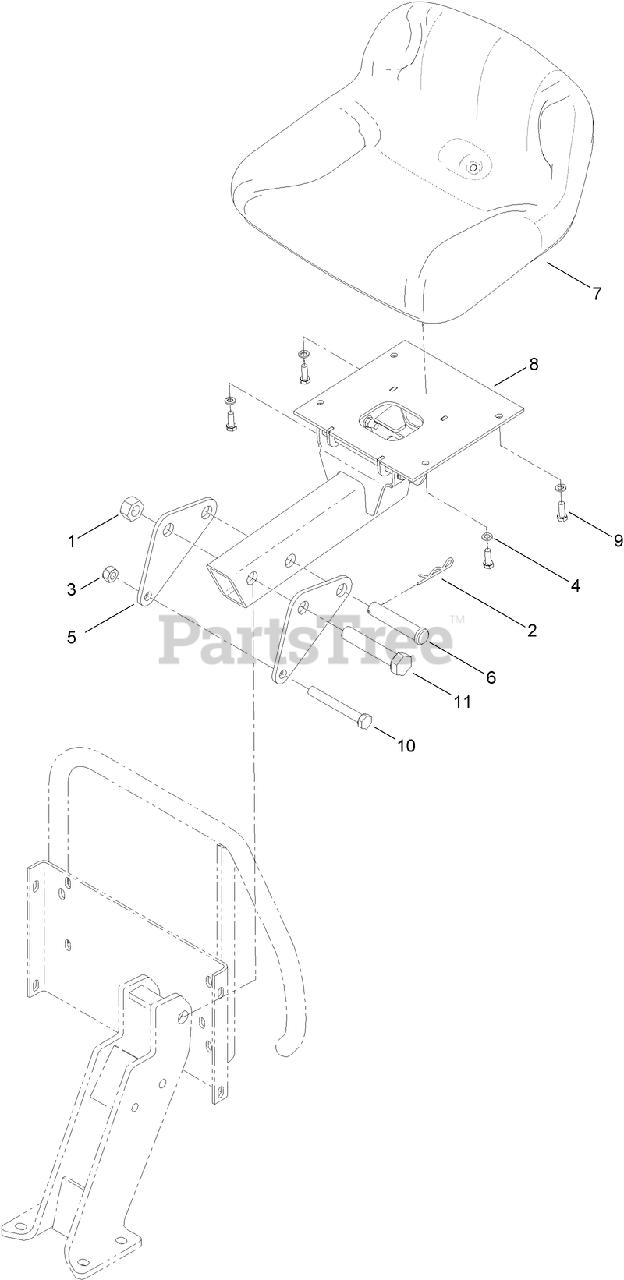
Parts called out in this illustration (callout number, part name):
1	NUT-LOCK
2	PIN-HAIR COTTER, INT
3	NUT-LOCK, HEX
4	WASHER-LOCK
5	PLATE-SEAT MOUNTING
6	PIN-MOUNT, SEAT
7	SEAT-BLACK, LOW-BACK
8	SEAT POST KIT
10	SCREW-HH
